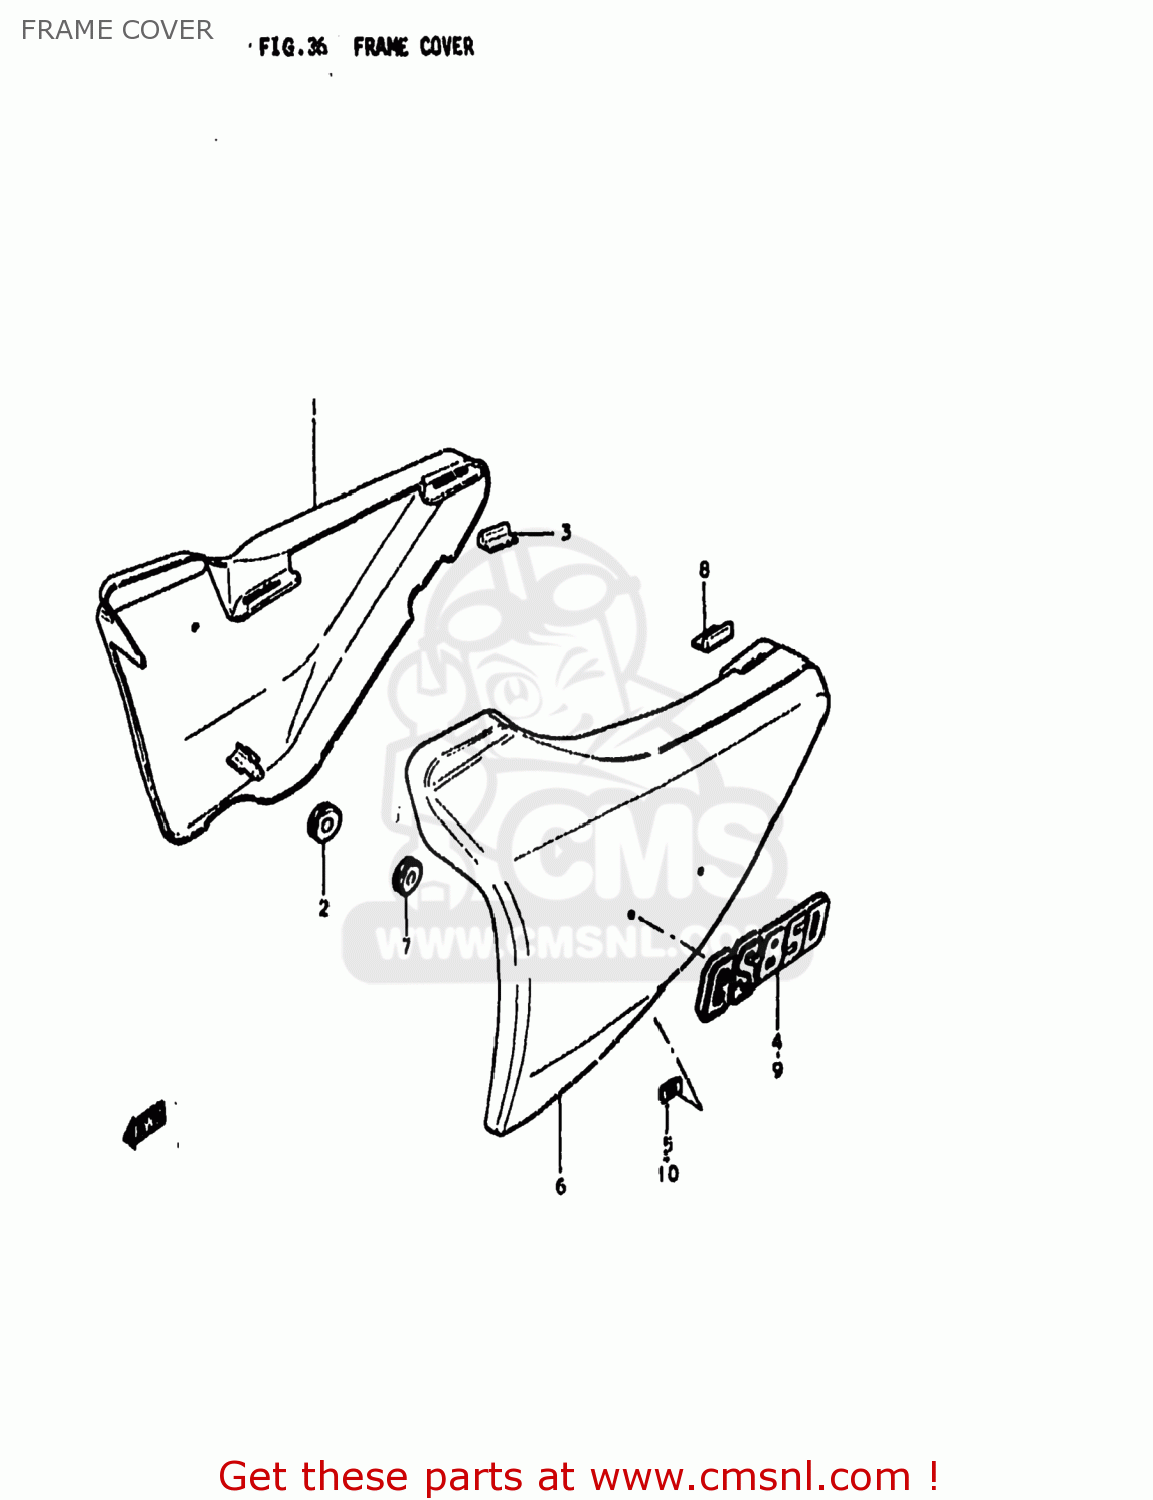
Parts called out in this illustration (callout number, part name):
1	COVER,FRAME,RIGHT
2	CUSHION
3	CUSHION,FRAME COVER
4	EMBLEM,FRAME COVER
5	NUT
6	COVER,FRAME,LEFT
7	CUSHION
8	CUSHION,FRAME COVER
9	EMBLEM,FRAME COVER
10	NUT
